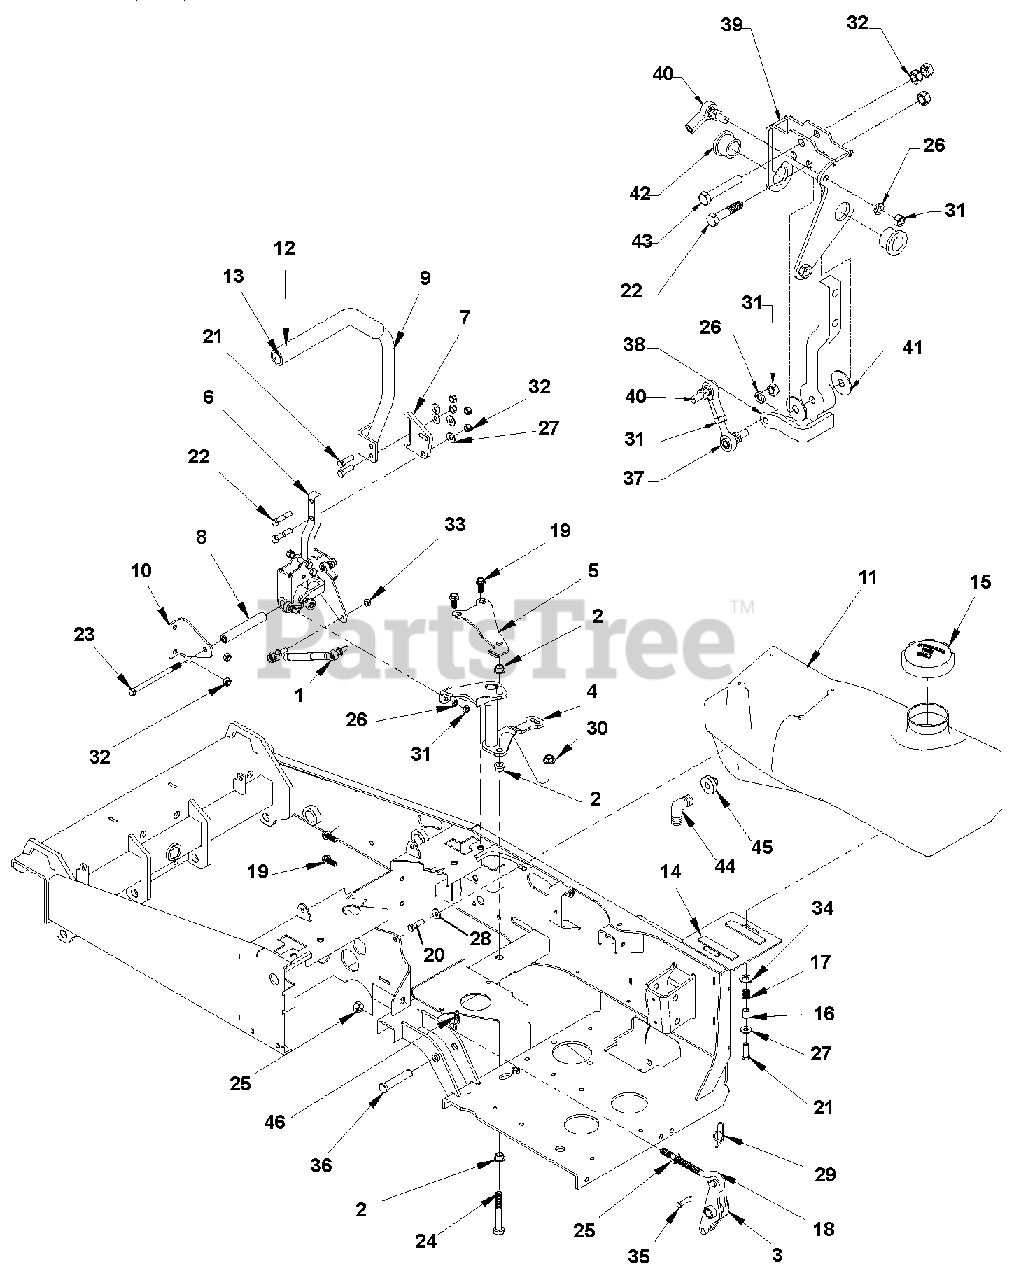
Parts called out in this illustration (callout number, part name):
1	Dampner, Steering Control
2	Bearing Shield 1/2"
3	Spring Pivot Weldment
4	Park Brake Control Arm RH
5	Ear, RH Brake Pivot
6	Handle Assembly RH
7	Handle Height Plate
8	Tube, Round .750 x .179 x 4.69
9	Weldment, RH Steering Handle
10	Plate, Bent
11	Fuel Tank, RH S/O w/Fittings (Includes items 15, 44, 45)
12	Grip, Foam
13	Plug, 7/8" End
14	Foam, 1/8 X 3/4 X 4.0 Long
15	Cap, Unleaded Fuel
16	Spacer, Gas Tank Attachment
17	Spring, COM .660 X .067 X .625
18	Eyebolt - .5 X 6.9
19	Bolt, 3/8-16 X 1.00 FGH 8
20	Bolt, 3/8-16 X .750 Hex 5
21	Bolt, 3/8-16 X 1.25 Hex Grade 5
22	Bolt, 3/8-16 X 1.75 Hex 5
23	Bolt, 3/8-16 X 5.50 Hex 5
24	Bolt 1/2-13 X 2.75 G5
25	Nut, 1/2-13 STD Hex GR5
26	Washer, .313 MED Spring Lock
27	Washer, .313 Reg Flat
28	Washer, .375 Reg Flat
29	Ring, Rue .375 x .054 x 1.254
30	Locknut, 1/2-13 Crown
31	Nut, 5/16-24 STD Hex GR5
32	Locknut, 3/8-16 Crown
33	Locknut, M8-1.25 Crown
34	Washer, .500 X 1.00 X .105 FLAT
35	Pin, CVS .375 X 1.38 X 1.14
36	Pin, CVS .625 X 3.00 X 2.77
37	Ball Joint RH 5/16 Male W/ STD
38	Bar Weldment RH Steering
39	Handle Control Weldment, RH
40	Ball Joint, RH 5/16 Female W/STD
41	Nylon Washer, 1.27OD x .400 ID
42	Bushing, .750 x 1.00 x .750
43	Bolt, 3/8-16 x 2.25 Hex 5
44	Fitting, 90 1/4 Hose x 1/2 Hose S/O
45	Grommet, Rubber
46	Ring, Rue .625 x .072 x 1.690
